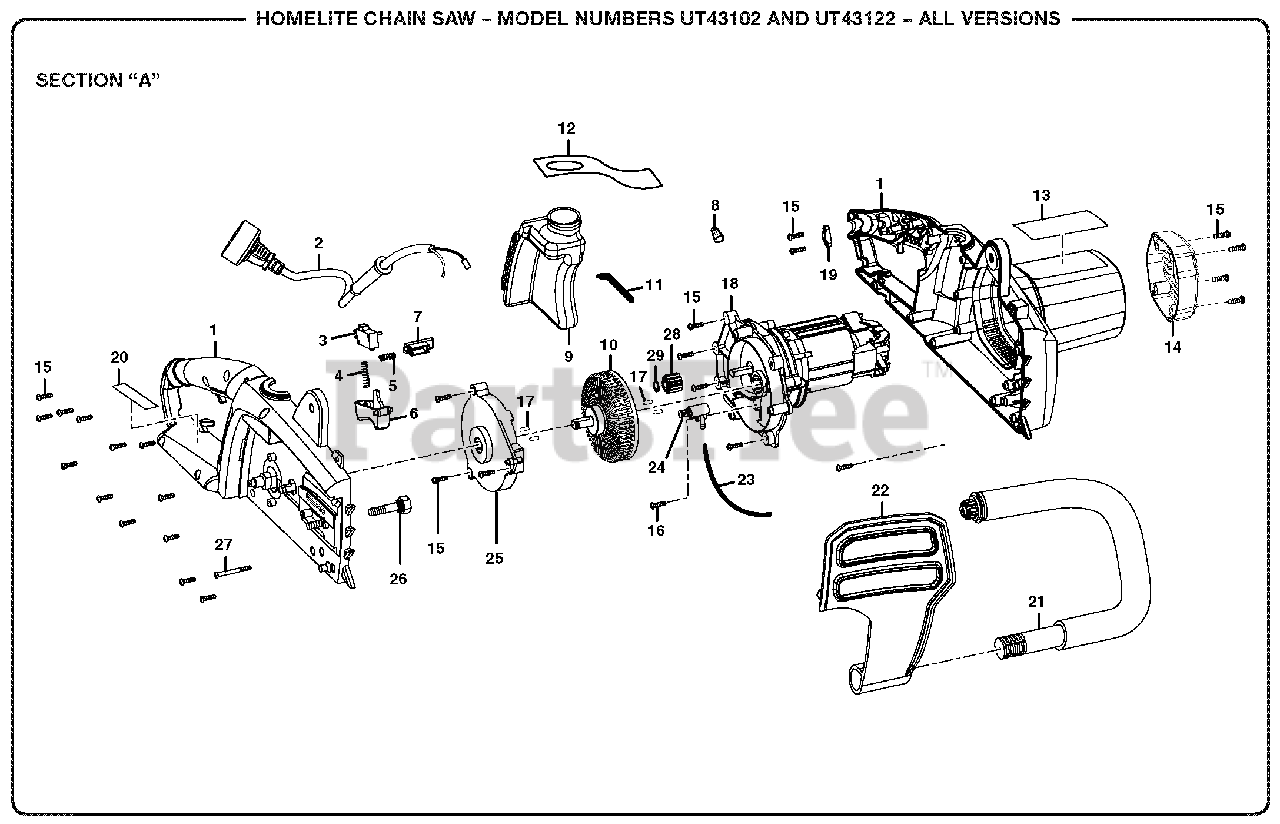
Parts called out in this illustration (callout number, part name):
1	Housing Assembly
2	Power Cord
4	Trigger Spring
5	Lock-off Spring
7	Lock-off Button
9	Oil Reservoir Assembly
10	Ring Gear Assembly
11	Inlet Oil Tube
12	Hang Tang
13	Data Label (UT43102)
14	Motor Cap (UT43102)
15	Screw (M4 x 14 mm)
16	Screw (M3.8 x 14 mm)
17	Rubber Pin
18	Motor Assembly (UT43102)
19	Cord Clamp
21	Front Handle
23	Outlet Oil Tube
25	Ring Gear Cover
26	Chain Bar Stud
27	Screw (M4.2 x 45 mm)
29	Retaining Ring
